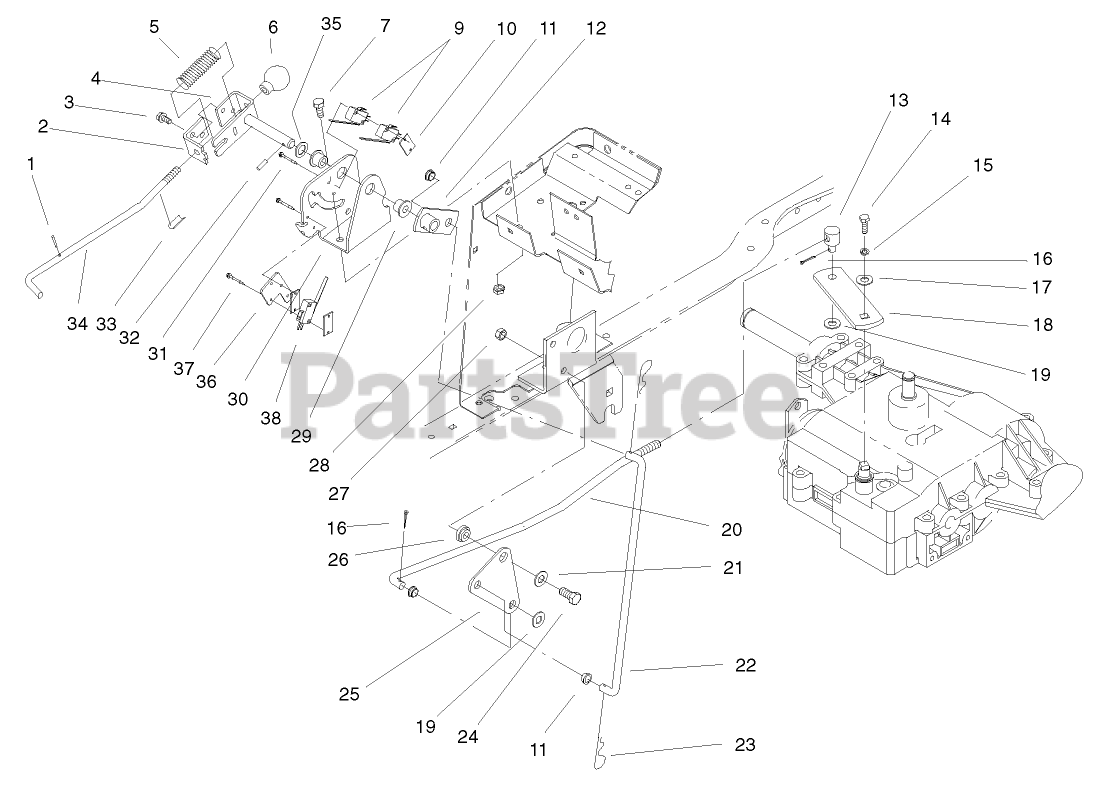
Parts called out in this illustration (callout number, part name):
2	BRACKET - SHAFT
3	SCREW-HWH
4	ARM-PIVOT
5	SPRING-COMPRESSION
7	SCREW-HH
9	SWITCH - CLUTCH
10	NUT-SPEED
12	TUBE-LINKAGE ASM
13	TRUNNION
14	SCREW-HH
15	WASHER-LOCK
16	PIN-COTTER
17	SPACER
18	BRK-TRASXL SHI
19	WASHER-FLAT
20	ROD - TRANSAXLE SHIFT
21	WASHER-FLAT
22	ROD - LINKAGE
24	SCREW-HH
25	BRACKET - PIVOT
26	BUSHING
27	NUT-LOCK, NI
28	NUT-LOCK, NI
29	BUSHING
30	BRKT-PIVOT MTG
31	SCREW-HH
32	PIN-ROLL, SLOTTED
33	DECAL - REVERSE GEAR
34	ROD - SHIFT
35	WASHER
38	SWITCH-MICRO
